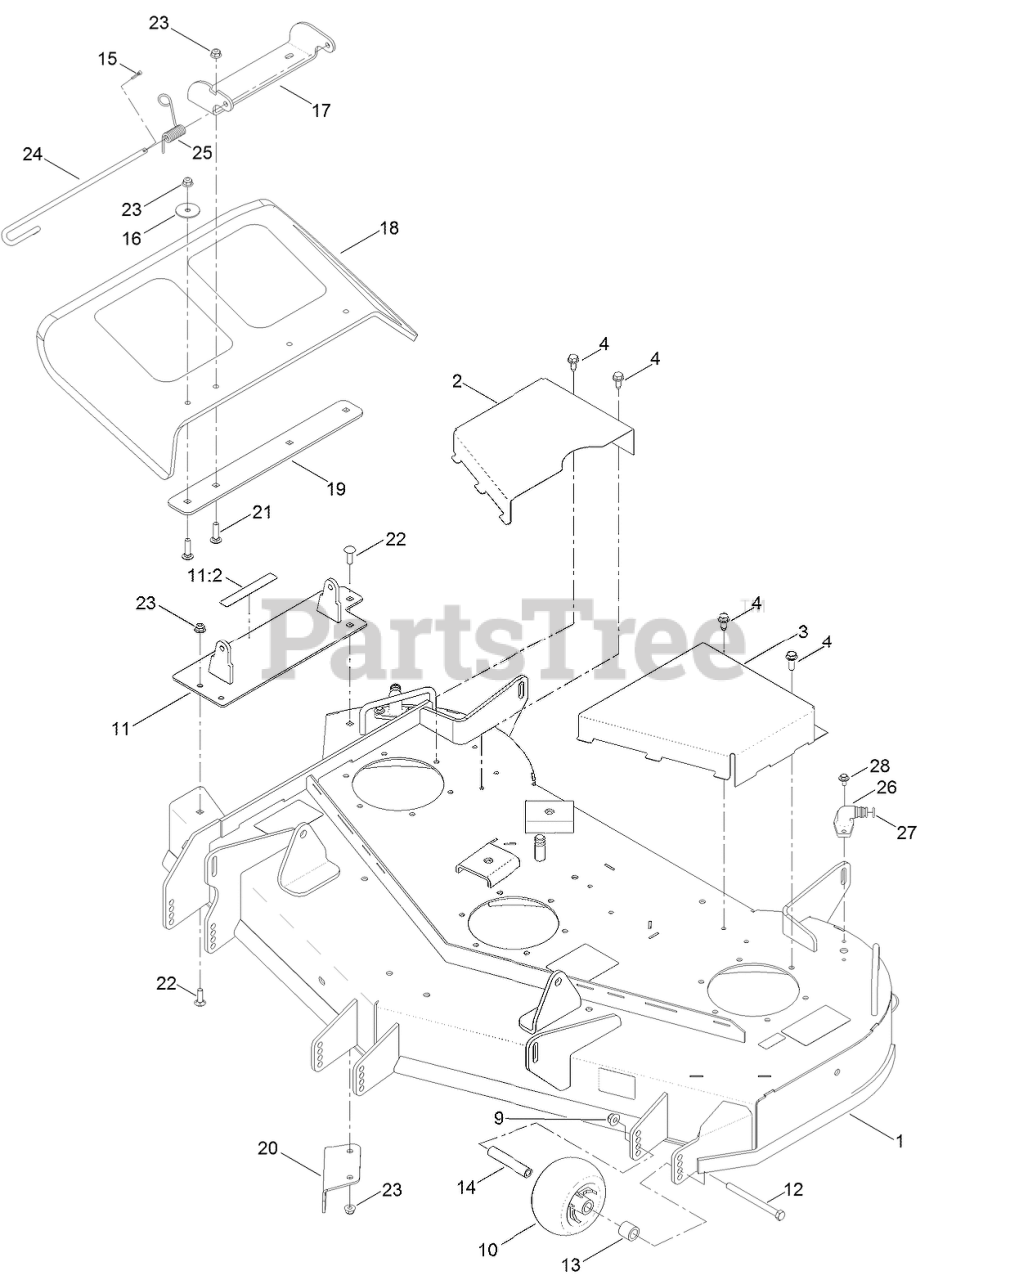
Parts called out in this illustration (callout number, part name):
1	48 INCH DECK ASM
2	COVER-BELT
3	COVER-BELT
4	SCREW-HWHTF
9	NUT-HF, NI
10	ROLLER-SCALP, ANTI
11	PIVOT-DEFLECTOR
11:2	DECAL-DANGER
12	SCREW-HH
13	SPACER-AXLE, REAR
14	TUBE-SPANNER
15	PIN-COTTER
16	WASHER-FLAT
17	BRACKET-DEFLECTOR, UPPER
18	DEFLECTOR
19	PLATE-DEFLECTOR
20	BAFFLE-CUTOFF
21	SCREW-CARR
22	SCREW-CARR
23	NUT-HF, NI
24	PIN-CHUTE
25	SPRING-TORSION
26	FITTING-WASHOUT
27	O-RING
28	SCREW-HHFTF
